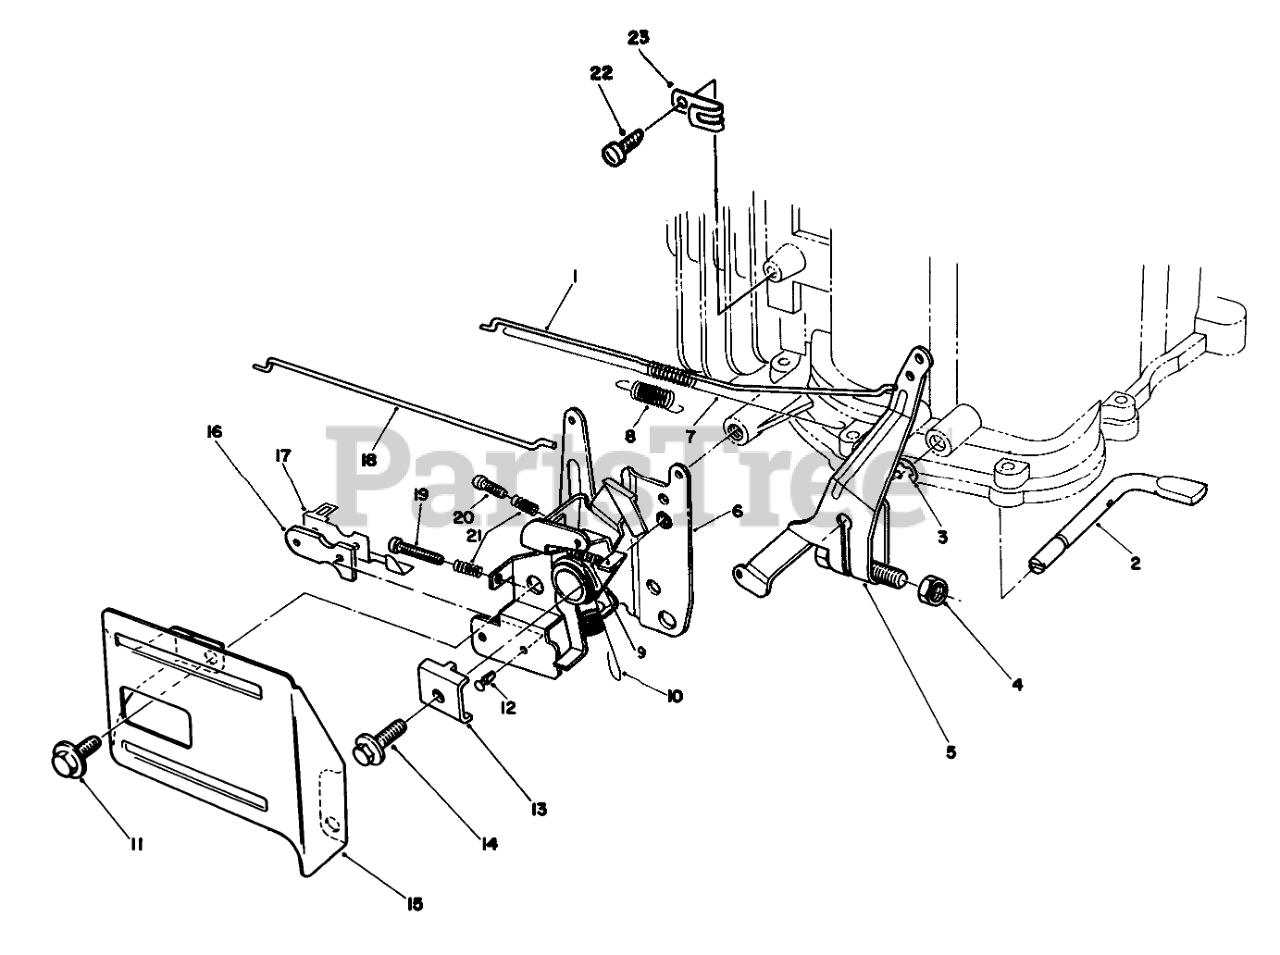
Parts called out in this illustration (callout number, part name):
1	Rod-Carburetor
2	SHAFT
3	E-RING
5	ARM ASM
6	THROTTLE
7	SPRING
8	SPRING
9	SPRING
10	SPRING
12	RIVET
13	CLAMP-CABLE
15	THROTTLE GUARD
16	INSULATOR-KILL SWITCH
17	TERMINAL-KILL SWITCH
18	Rod-Choke
19	SCREW
20	SCREW
21	SPRING
22	SCREW
23	Clamp
